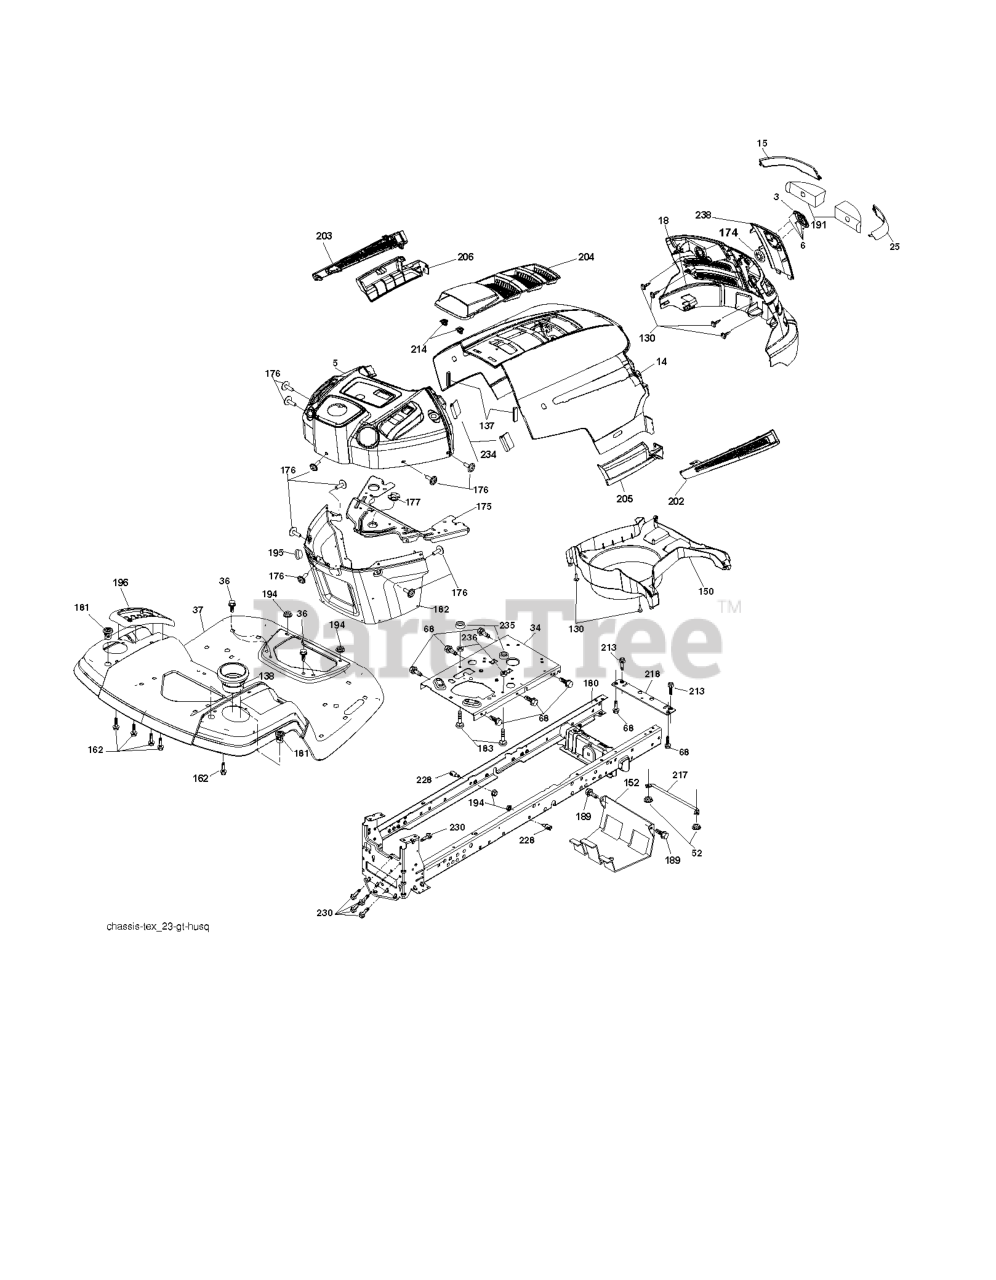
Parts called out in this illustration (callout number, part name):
3	RP LOGO
5	DASH
14	HOOD
15	LENS.HUSQVARNA LT.LH
18	RP GRILLE/LENS ASM.
25	LENS.HUSQVARNA LT.RH
34	PLATE.ENGINE.WELDED.CHASSIS
36	SCREW 3/8-16X3/4
37	FENDER.REAR.ORANGE
52	LOCKNUT
68	Screw 5/16-18 x 1/2 Hex, Self Tapping 5/16-18 x 1/2
130	SCREW
137	BUMPER DASH
138	CUPHOLDER.TL.TEX.418
152	SHIELD.BROWNING.W/TEX
162	SCREW.HI-LO.CONSOLE
175	CROSSMEMBER
176	SCREW.#10-24X5/8.RN.QU
177	BUSHING STEERING
180	CHASSIS
181	BUSHING.MNT.FEND.CRGO.
182	DASH LOWER
183	BOLT.5/16-18X1-1/4 FULL.THREAD
189	SCREW
191	INSERT REFLECTIVE
194	NUT LOCK HEX FLANGE 5/16-18
195	PLUG DASH
196	CONSOLE.ASM.DECK.LIFT.
202	VENT SIDE HOOD RH
203	VENT SIDE HOOD LH
204	VENT TOP HOOD
205	SKIRT SIDE RH
206	SKIRT SIDE LH
213	BOLT
214	CLIP.RETAINER.TINNER.
217	ROD PIVOT CHASSIS/HOOD
218	X-PIECE.HOOD.STOP.NON/
228	STUD.FASTNER.W/ANTI-ROTATE
230	SHOULDER BOLT 5/16-18TT
234	BUMPER.HOOD.TEX.HUSQVARNA
235	SPACER FENDER
236	NUT.CENTERLOCK.5/16-
238	TRIM
239	NUT PUSH M
